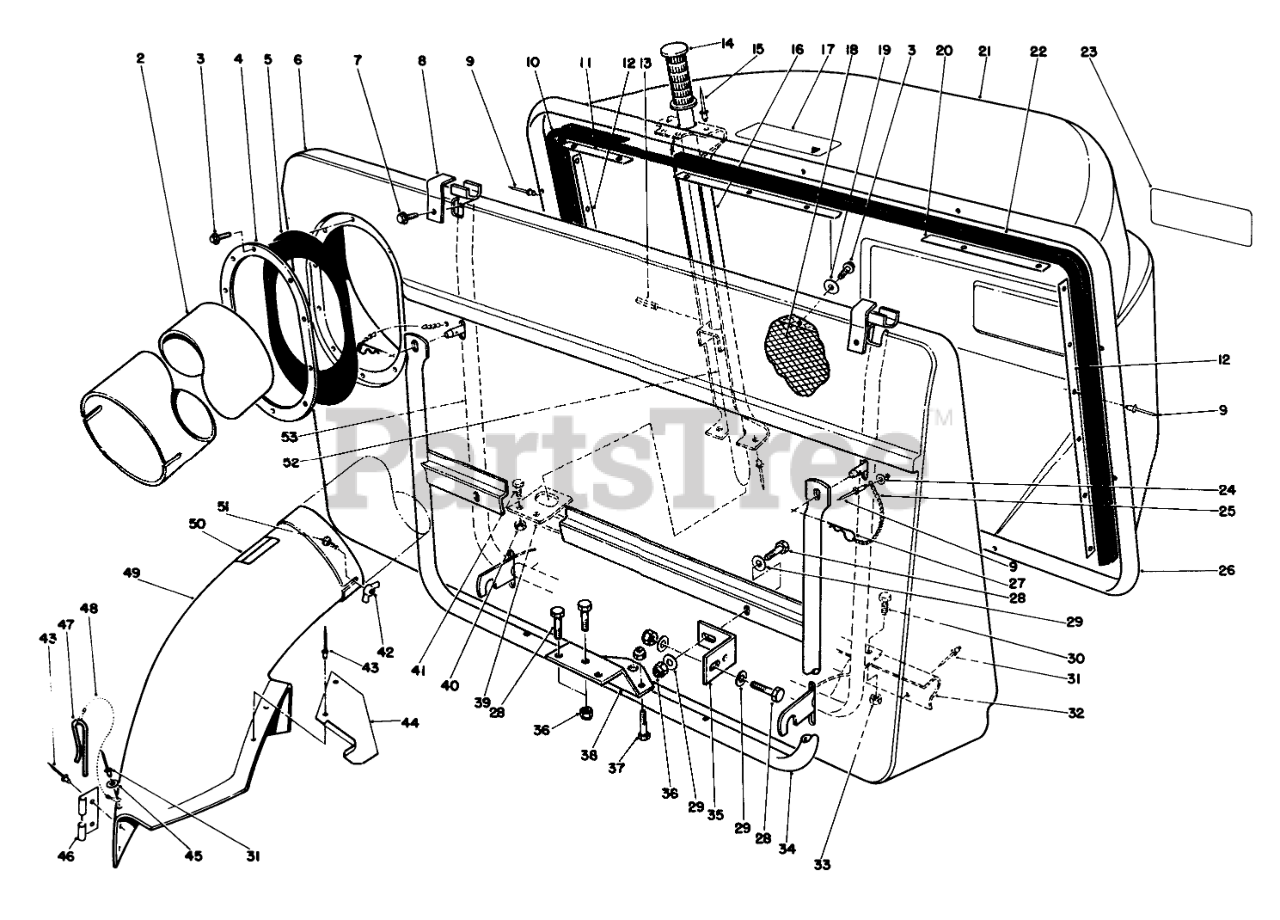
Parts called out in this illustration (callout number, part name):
2	TUBE(ROUND&LONG)
3	SCREW-HWHTF
4	RING-RETAINING
5	RING-RETAINER, RUBBER
6	Bag Front
7	SCREW-HWH
8	RETNR PIVOT BRKT
10	RH BAG SEAL
11	RETNR TOP EXT.
12	BAG RETNR EXT.
13	PIN-ROLL
16	DUMP HDLE CHANL WA
17	Decal Warning
18	Screen Bag
19	WASHER-FLAT
20	EXTRUSION BAG RETAINER
21	REAR GRASS BASKET
22	Seal-Bag LH.
23	EASY EMPTY BAG DECAL
24	WASHER
25	10 LINK CHAIN W/O HOOK
26	BAG SUPT ASM FRM
27	PIN-HAIR
28	SCREW-HH
29	WASHER-PLAIN
30	SCREW-HH
31	RIVET-BLIND
32	FRAME SUPT BRKT B
33	NUT-LOCK, CONE
34	BAG SUPPORT WA
35	MTG BRACKET
36	NUT-LOCK, NI
37	SCREW-HH
38	MTG PLATE B
39	Hanger-Frame Lower
40	NUT-LOCK, CONE
41	SCREW-HH
42	NUT-WING SPECL
43	RIVET-BLIND
44	CHUTE SUPT BRKT
45	WASHER-PLAIN
46	BRACKET-MOUNTING, CHUTE
47	PIN-LOCKING, CHUTE
48	LANYARD
49	Chute Assembly (Incl. Ref. #31, 41-50)
50	DECAL-DANGER
51	BOLT-CARR
52	DUMP HANDLE ASM
53	Bag Frame
